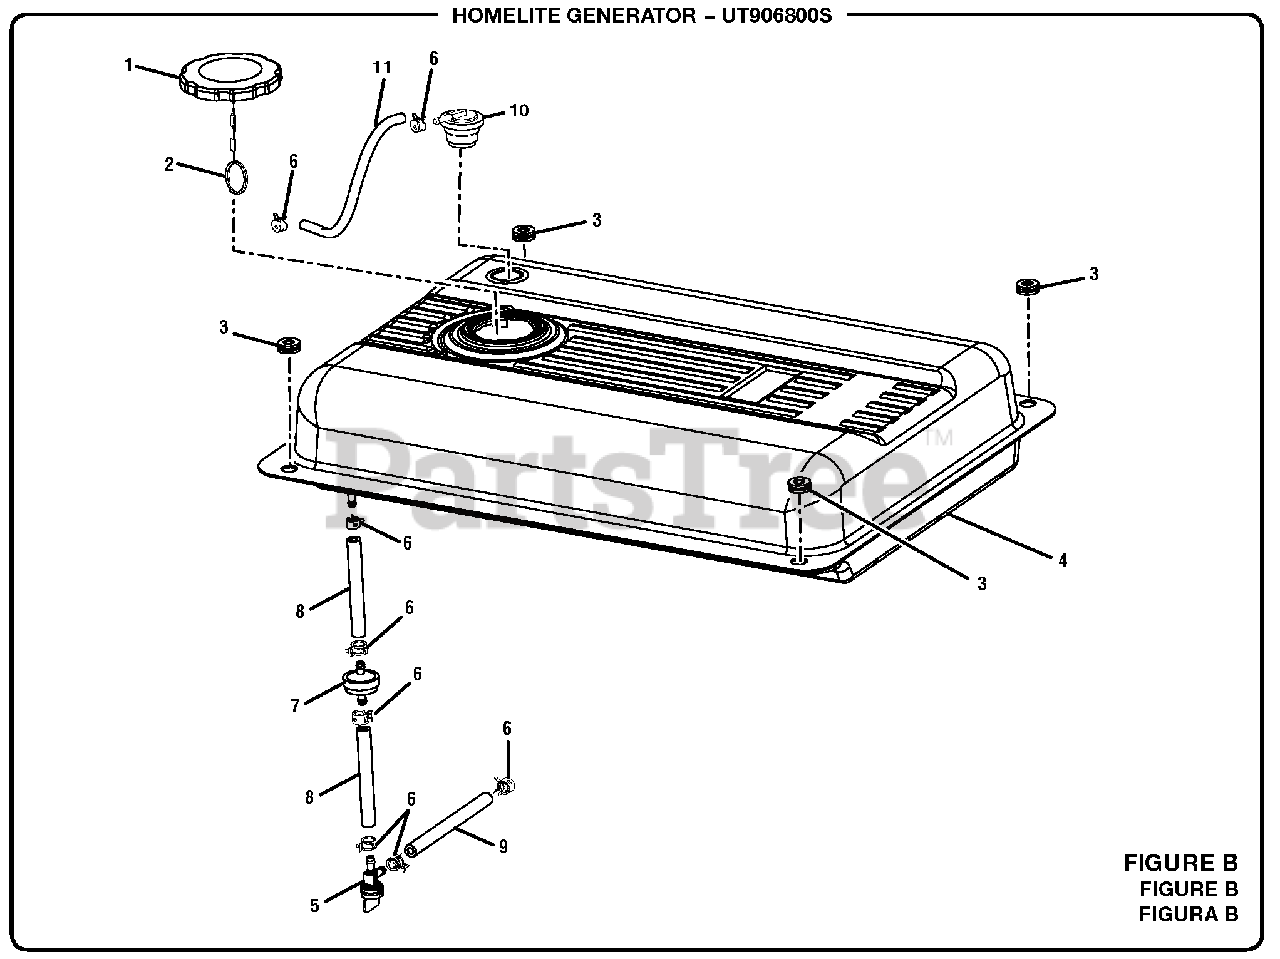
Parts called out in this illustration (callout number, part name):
1	Fuel Tank Cap
2	Fuel Tank Screen
3	Bushing w/Insert
4	Fuel Tank
5	Fuel Valve
6	Fuel Line Clamp (1/2 in.)
7	Fuel Line Filter
8	Fuel Line (1/4 in.)
9	Fuel Hose (5 mm)
10	Vapor Vent
11	Vapor Hose
